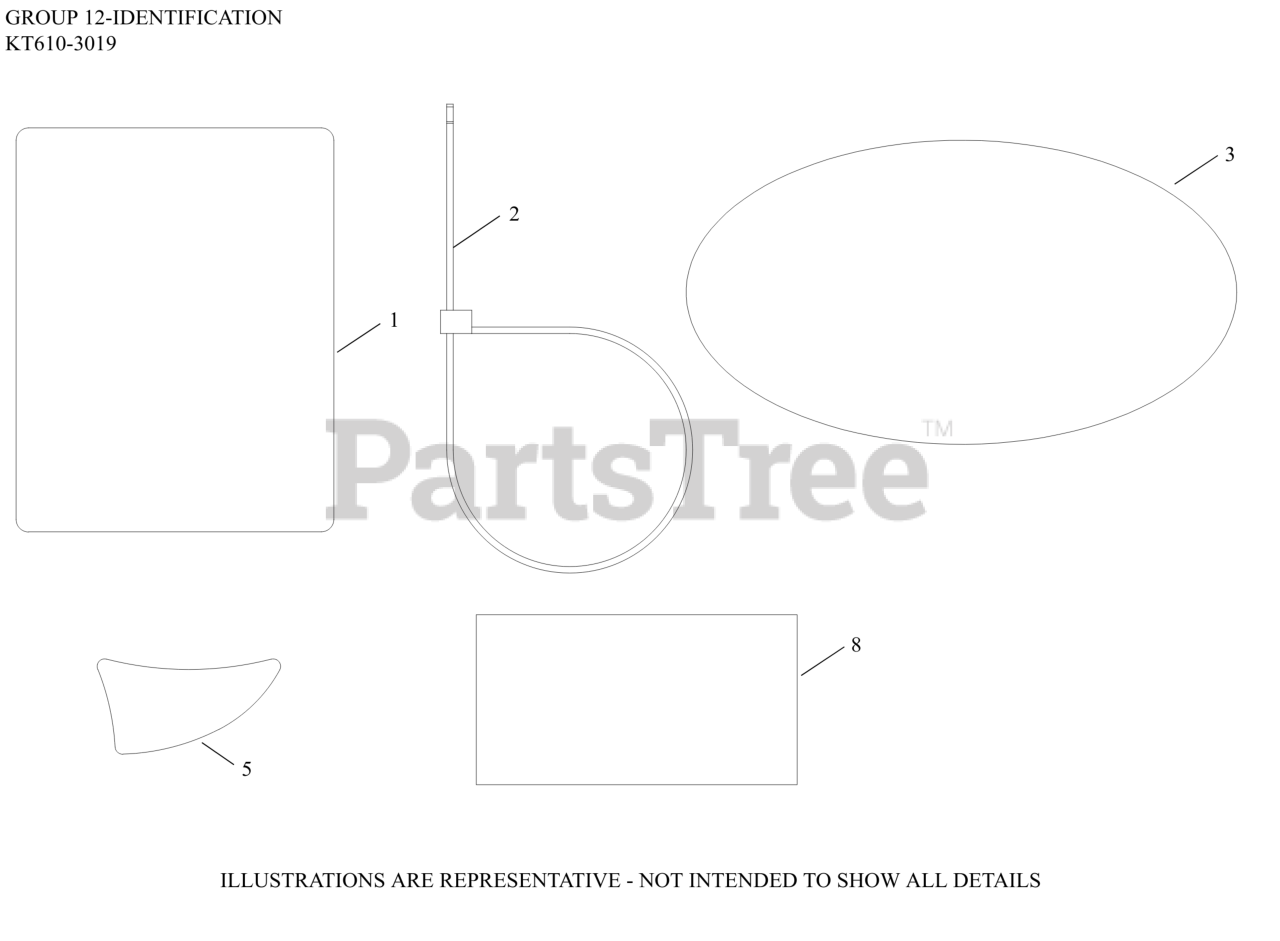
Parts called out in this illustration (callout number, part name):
1	LABEL, CLEAR LAMINATION
3	LABEL, 6600 SERIES (19HP)
3	LABEL, PRO PERFORMANCE FILTRATION SYSTEM
5	LABEL, SMART CHOKE
8	DECAL, USA
